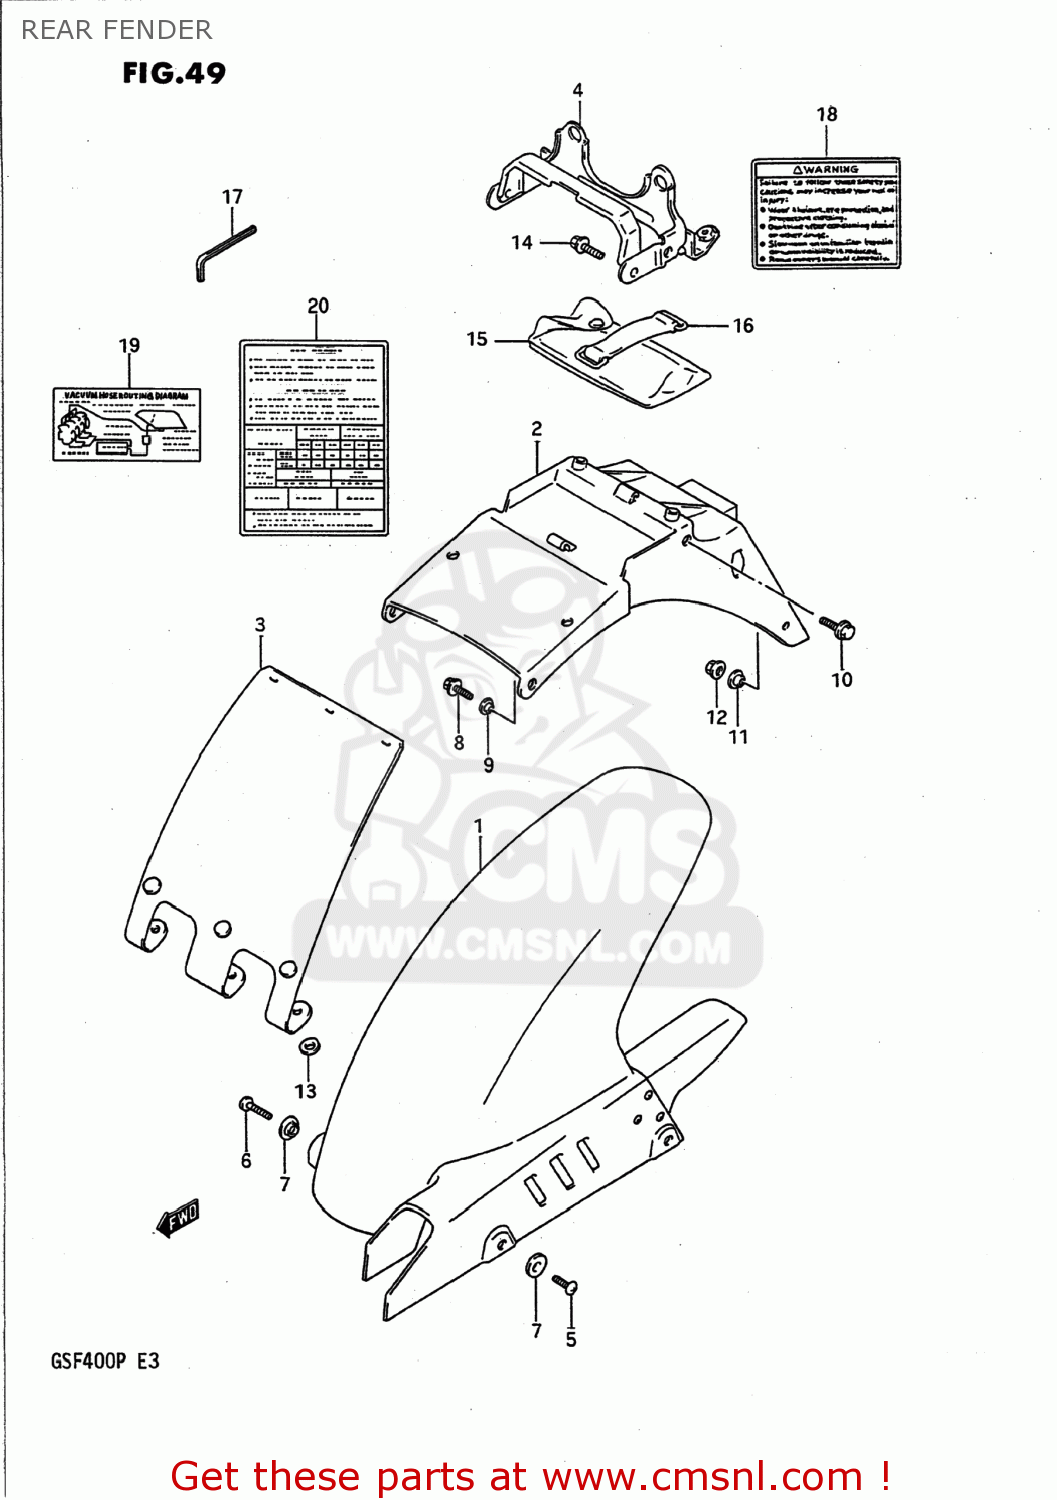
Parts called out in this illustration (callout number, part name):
1	FENDER,REAR
2	BODY,RR FENDER UPR
3	MUDGUARD ASSY,RR FENDER
4	BRACKET,FRAME COVER
5	SCREW 6X12
6	SCREW
7	WASHER
8	BOLT 6X16
9	WASHER
10	BOLT 8X30
11	WASHER
12	NUT
13	WASHER
14	BOLT 6X16
15	TOOL SET
16	BAND
17	SPANNER,HEXAGON(4)
18	LABEL
19	LABEL (VACUUM HOSE ROUTING)
20	LABEL (TIRE AIR PRESSURE)
